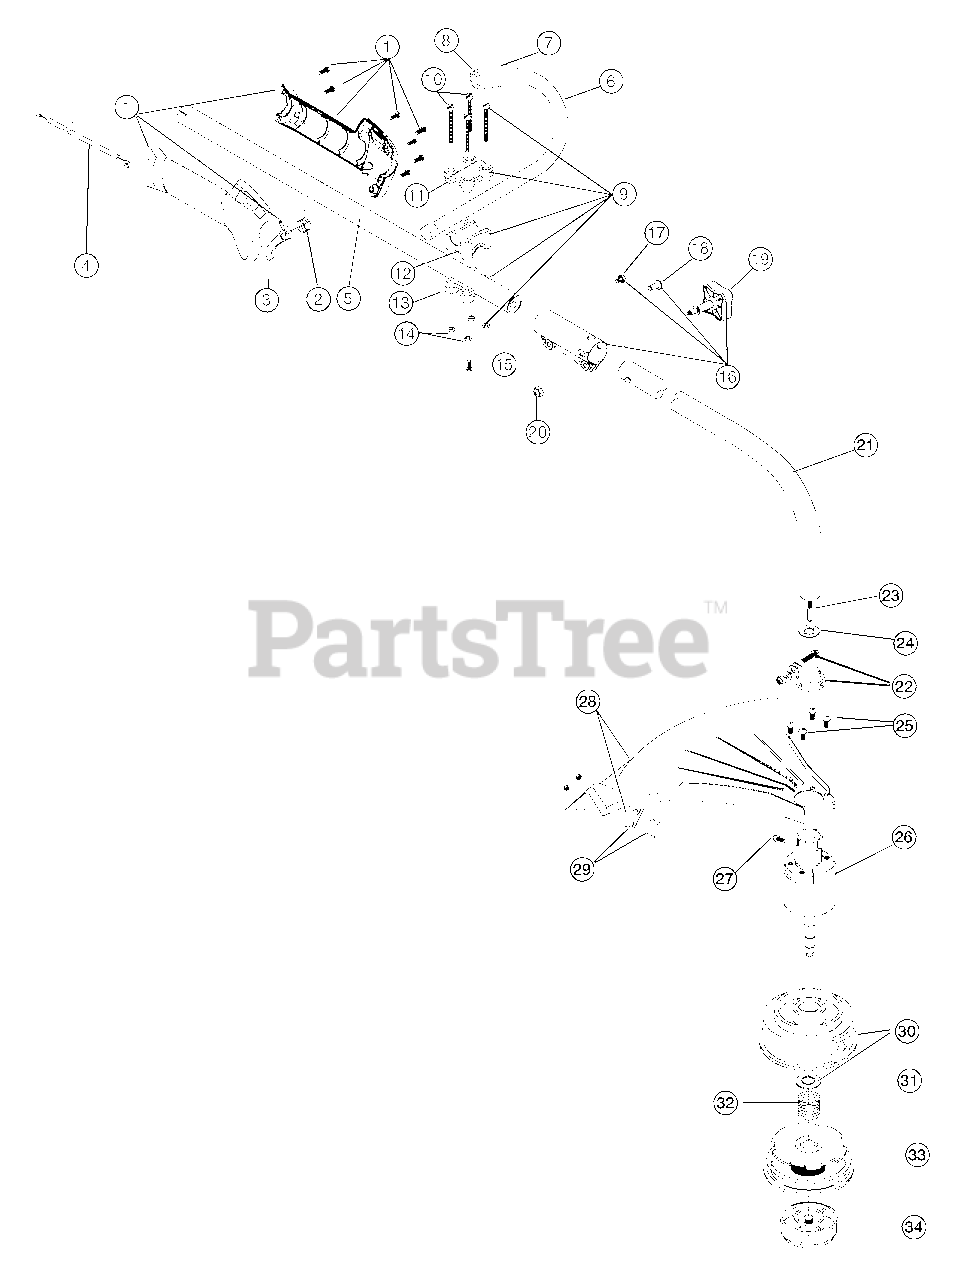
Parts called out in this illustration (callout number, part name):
1	Throttle Housing and Trigger Assembly
2	Throttle Trigger Spring
3	Throttle Trigger
4	Throttle Cable Assembly
5	Upper Drive Shaft Housing Assembly
6	J-Handle Assembly
8	Tube Closure
9	Handle Bracket Assembly
11	Upper Handle Clamp
12	Middle Handle Clamp
13	Lower Handle Clamp
15	Anti-Rotation Screw
16	Click-Link Coupler
19	Adjustment Knob
20	Knob Retaining Nut
21	Lower Drive Shaft Housing Assembly
22	Lower Clamp Assembly
23	Lower Flexible Drive Shaft
24	Palnut
25	Shield Mounting Screw
26	Bushing Housing Assembly
27	Anti-Rotation Screw
28	Shield and Blade Assembly
29	Blade Assembly
30	Outer Spool and Eyelet Assembly
31	Retainer
32	Spring
33	Inner Reel
34	Bump Head Knob Assembly
